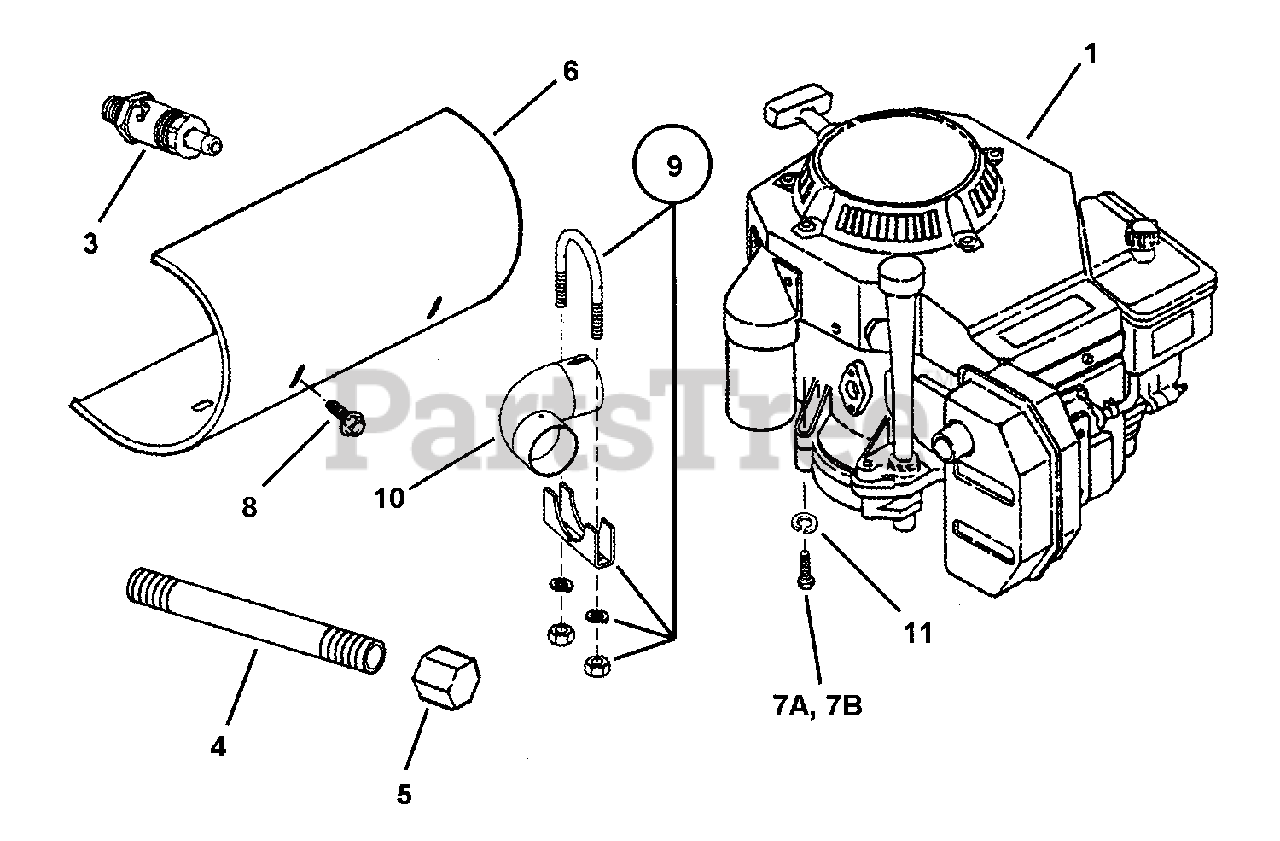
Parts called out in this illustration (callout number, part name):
1	* ENGINE, 14HP Kawasaki
1	* ENGINE, 14HP Kohler
1	* ENGINE, 14HP Kawasaki Electric Start
1	* ENGINE, 15HP Kohler
1	* ENGINE, 15HP Kawasaki
1	* ENGINE, 17HP Kawasaki
1	* ENGINE, 22HP Kohler
1	* ENGINE, 23HP Kohler
3	ASSEMBLY, Oil Valve
4	PIPE, Oil
5	CAP, Oil Drain
6	HEAT SHIELD
7A	BOLT, M8-1.25 X 25MM GD8.8
7B	SCREW, 5/16-18 x 1-1/2" Hex Head Cap, GR 5
8	SCREW, #8-18 x 9/16" Hex Washer Self-Tap
9	ASSY, Clamp (Incl. Clamp, U-Bolt, 2 Split Lock Washers & 2 Hex Nuts)
10	ELBOW, Exhaust
11	WASHER, .32 x .58 x .08 Split Lock
